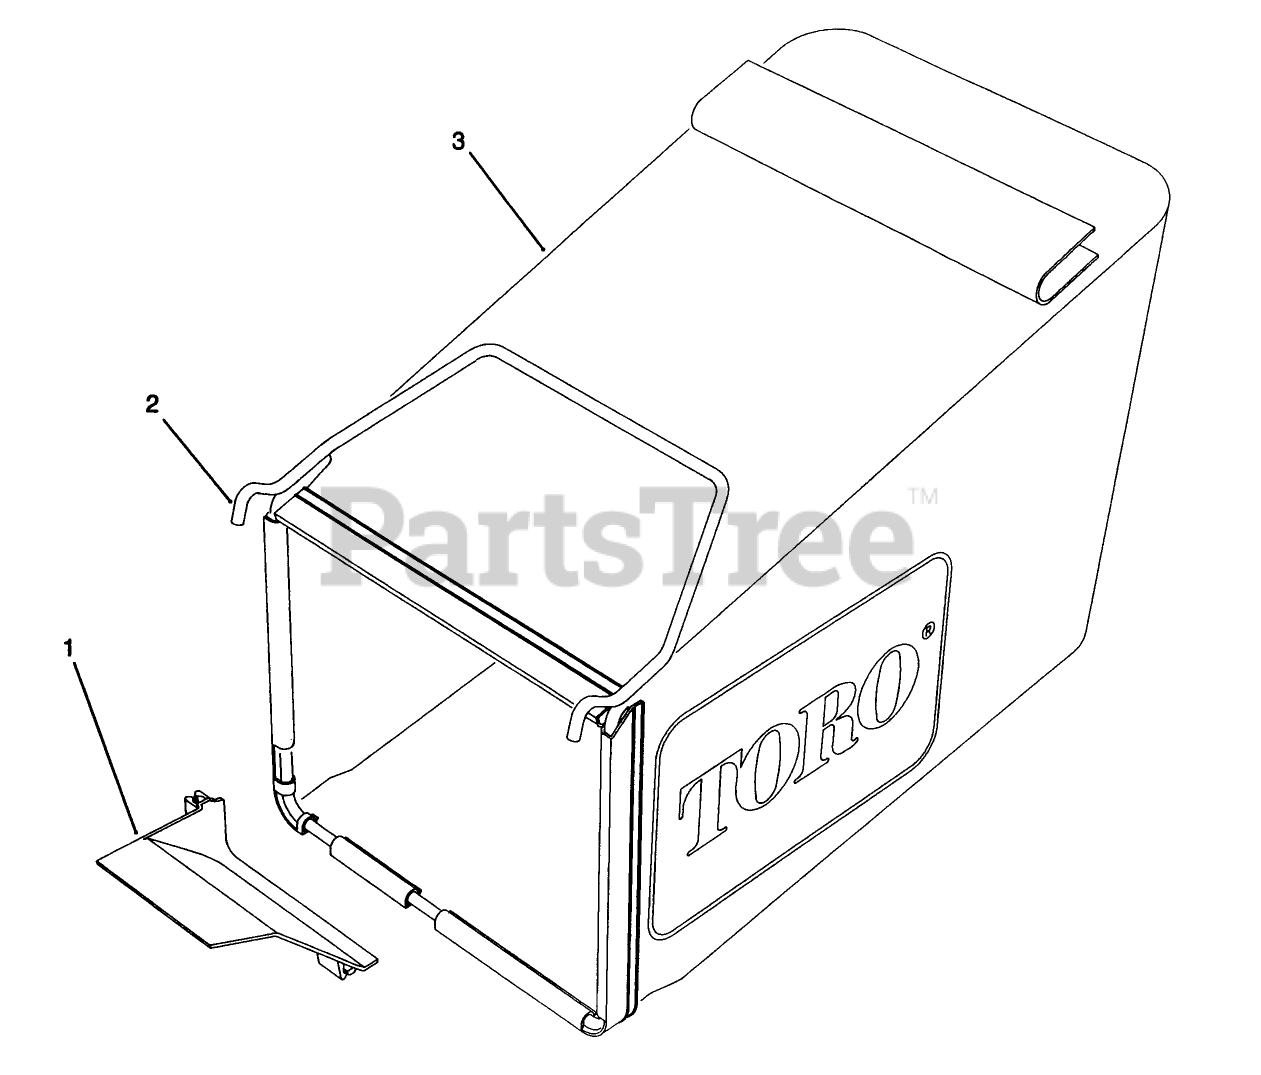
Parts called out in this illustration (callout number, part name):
1	BAG RAMP
2	FRAME WA
3	GRASS BAG REAR EMPTY
